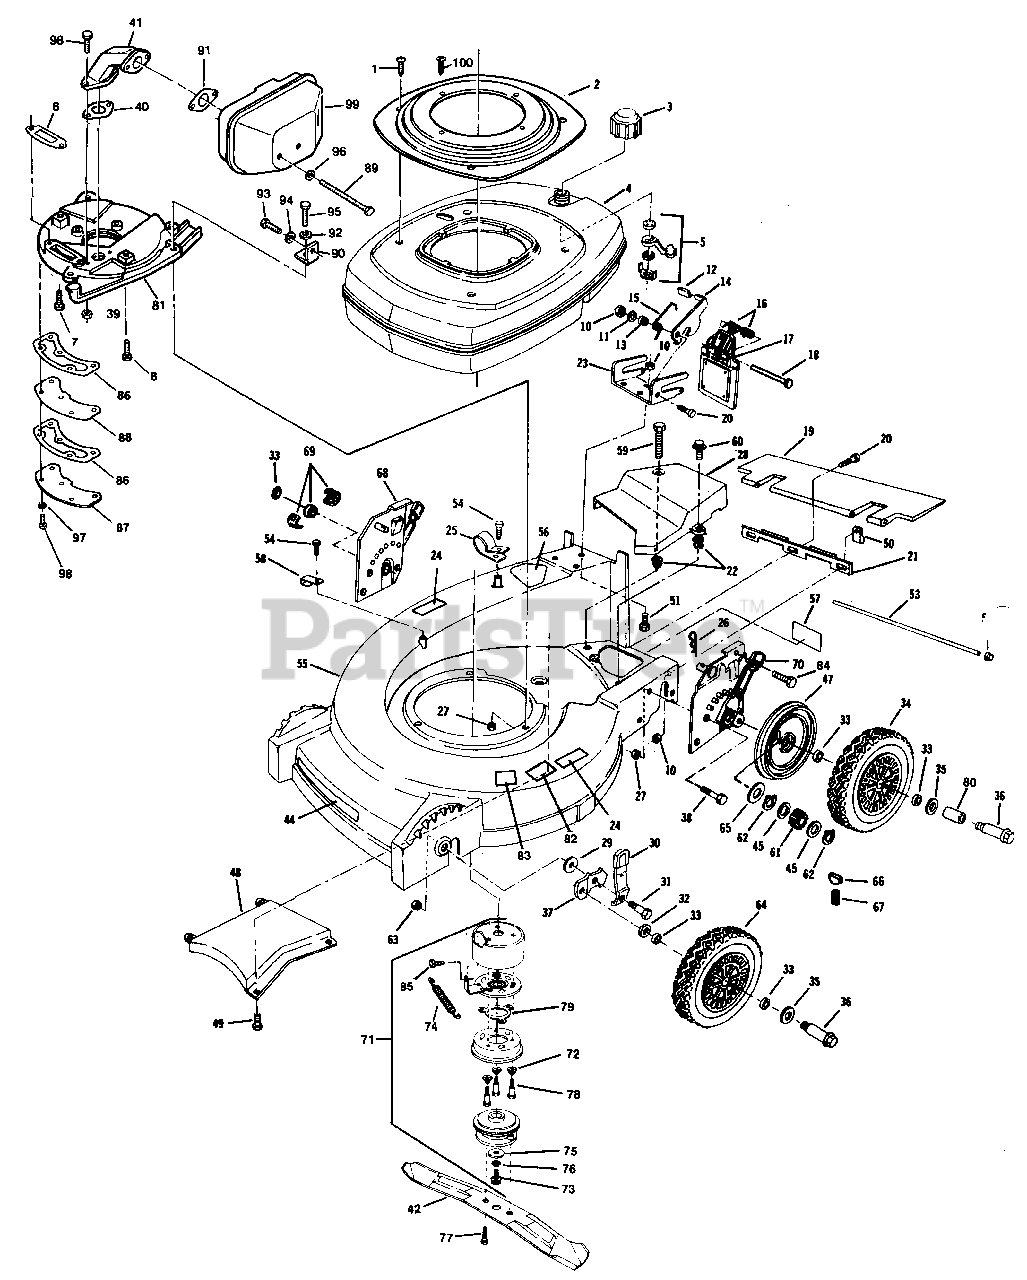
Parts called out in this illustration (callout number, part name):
1	Screw
2	Cover-Shroud
2	Starter Base & Nut Assy.
3	Fuel Cap
4	Shroud-Engine
4	Shroud Tank & Valve Assy.
5	Fuel Shut-Off Assemby
6	Gasket-Exhaust
7	Screw-MuMer to Block
8	Screw-Muffler Plate to Block
9	Screw-Muffler Plate to Housing
10	Nut-Latch Brk't. and Trailing Shield
11	Washer
12	Knob-Latch
13	Stepped Spacer
14	Catch-Bag
15	Spring-Latch
16	Spring
17	Door
18	Rod
19	Shield-Trailing
20	Screw-Latch Bracket and Trailing Shield
21	Bracket-Bag Hanger
22	Grommet
23	Hinge Plate
24	Decal-Ht. Adj.
25	Clamp-Cable and Primer Hose to Housing
26	Pin
27	Nut-Ht. Adj. to Hous. and Muff. Plate to Hous.
28	Cover Belt
29	Washer-Wheel Ht. Adj.
30	Knob and Spring Assembly
31	Bolt-Shoulder
32	Washer
33	Washer-Felt
34	Wheel and Tire Assembly 8" S.P.
35	Washer-Wheel Bolt
36	Bolt-Shoulder Wheel
37	Bracket-Wheel Ht. Adj.
38	Bolt-Height Adjuster Assembly
39	Nut
40	Gasket-Exhaust
41	Pipe-Exhaust
42	Blade-20"
44	Decal-Clutch
45	Spacer
47	Cover-Wheel
48	Baffle
49	Screw
50	Clamp-Rod
51	Screw-Truss Head
52	Nut-Rod
53	Rod-Trailing Shield
54	Screw-Clamp to Housing
55	Housing-20" Assembly
56	Decal-Blade Contact Warning
57	Decal-Caution
58	Clamp-Cable to Housing
59	Screw-Hex Hd.
60	Screw-Shoulder Idler
61	Pinion
62	Retaining Ring
63	Nut-Wheel Ht. Adj.
64	Wheel and Tire Assembly 8"
65	Washer
66	Key
67	Spring
68	Height Adjuster Assem.-R.H
69	Bearing and Retainer Ass'y.
70	Height Adjuster Assem.-L.H.
71	Clutch Assembly
72	Spring
73	Screw
74	Spring
75	Washer
76	Lockwasher
77	Screw
78	Screw
79	Gasket
80	Bushing
81	Mounting Plate
82	Starting Pad
83	Decal
84	Bolt
85	Bolt-Cable to Arm
86	Gasket-Muffler
87	Cover Gasket
88	BaMe
89	Screw
90	Bracket-Muffler
91	Gasket-Muffler
92	Washer
93	Screw
94	Washer
95	Bolt
96	Washer
97	Lockwasher
98	Screw-Locking
99	Muffler
100	Screw-Starter Mounting
